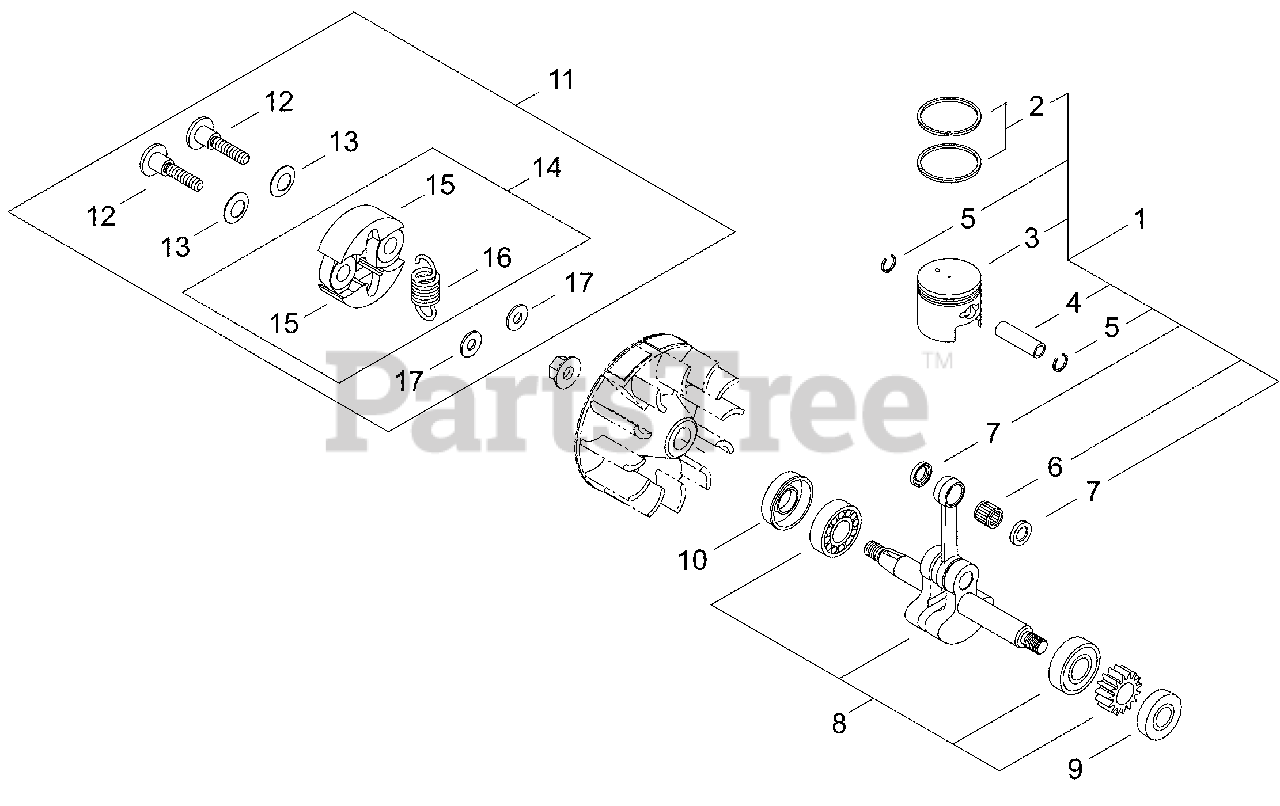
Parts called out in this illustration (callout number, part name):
1	PISTON KIT
2	RING, PISTON
3	PISTON
4	PIN, PISTON
5	RING, RETAINING
6	BEARING, NEEDLE
7	WASHER, THRUST - 10
8	CRANKSHAFT ASSY
9	SEAL, OIL - 12
10	SEAL, OIL
11	CLUTCH SHOE ASSY
12	BOLT, CLUTCH
13	WASHER - SPRING
14	CLUTCH SHOE ASSY
15	SHOE, CLUTCH
16	SPRING, CLUTCH
17	WASHER - 6
